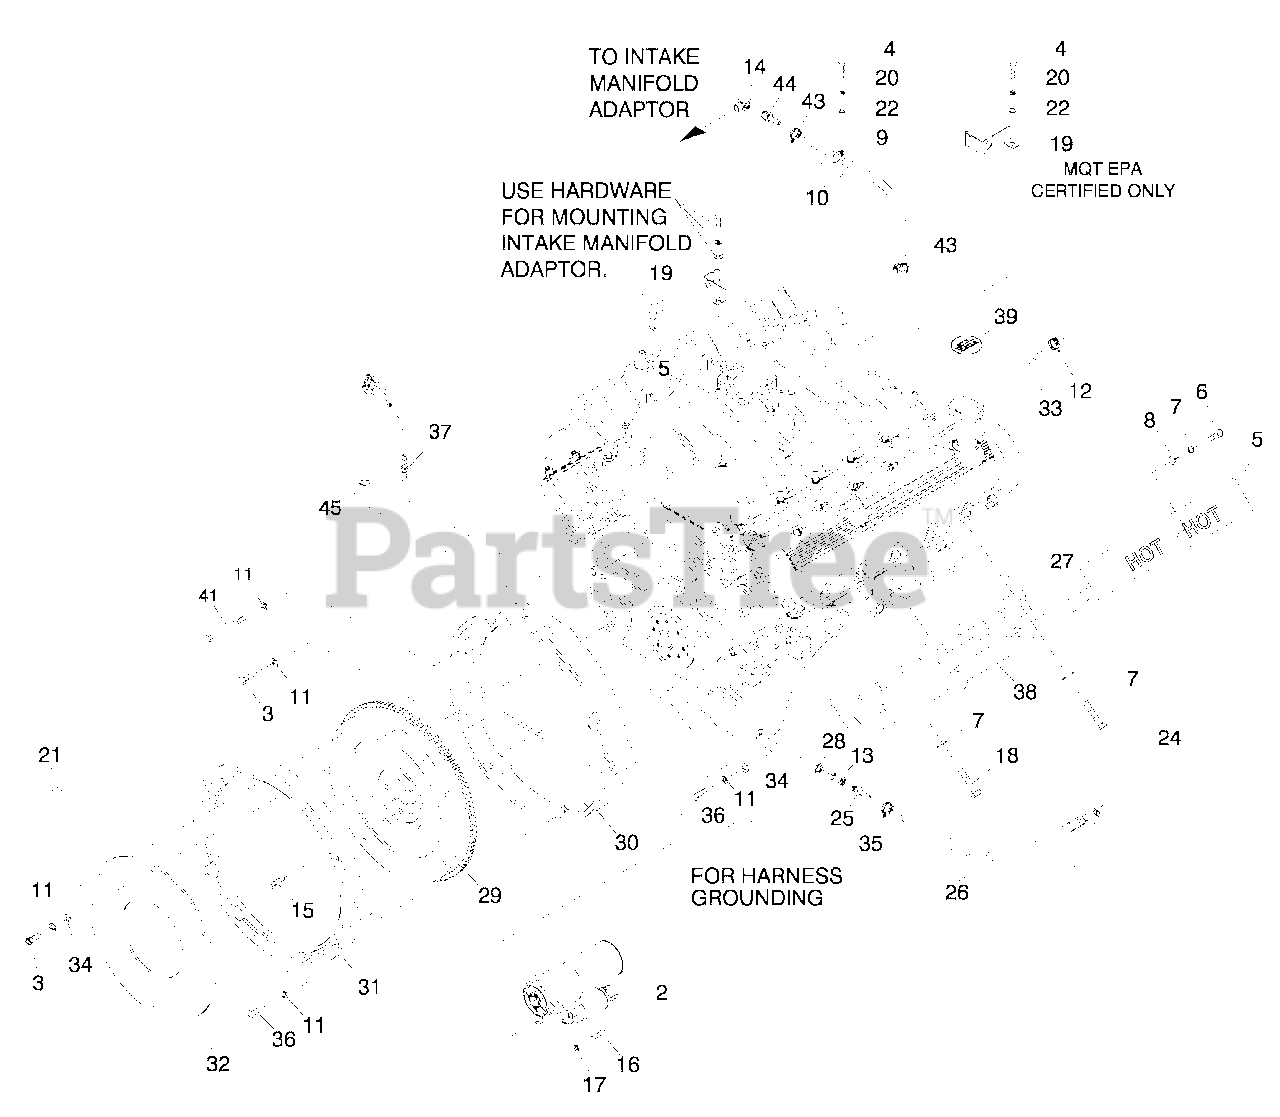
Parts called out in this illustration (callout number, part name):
2	STARTER MOTOR FORD V-10 ENGINE
3	SCREW SHC M10-1.5X 35 G12.9
4	SCREWHHCM6-1.0 X16G8.8
5	HEAT SHIELD EXHAUST
6	SCREW HHC 916-18X 1/2 SSTL
7	WAS HER LOCK M8SSTL
8	WAS HER FLAT M8 SS
9	CLAMPVINYL .75X.343Z
10	HOSE COOL 5(8" ID 250)WP (14")
11	WAS HER LOCK M10
12	CLAM PHOSE #10.56 - 1.06 (2300 & 3000RPM UNTSONLY)
13	ADAPTERM14-1.50 X3/8NPT
14	ELBOW 90D 1/4 NPT F-M BRASS
15	SCREW HHCM10-1.0 X 25 G10.9
16	SCREW SHC M8-1.25X30G12.9
17	WAS HER LOCK M8-5/16
18	SCREW HHCM 8-1.25 X 35 SSF-TH
19	BRACKET SIGNAL CONDITIONER
20	WAS HER LOCK M6-1/4
21	DOWEL PIN M10X24
22	WAS HER FLAT 1/4 ZINC
23	TIE WRAP UL7.4" X .19" BLK (NOTSHOWN)
24	SCREW SHC M8-1.25X35SS
25	BARBED STR 3/8NP TX3/8
26	HOSE DRAIN ASSY 28"
27	GASKET EXHAUST MANIFOLD
28	WAS HER NYLON .565
29	ASSEMBLY 68L G-BOX FLYWHEEL
30	FLYWH EE L H OUSING MAC H 6.8L V 10
31	COVER FLYWHEEL MACH 6.8L V-10
32	PLATE DAMPNER RETNR
33	CAP HOSE (2300 & 3000RPM UMTS ONLY)
34	WAS HER FLAT 3/8-M10 ZINC
35	CLAM PHOSE .38-.87
36	SCREW SHC M10-1.5X 25 G12.9
37	ASSY MAG PI CK U P(3/8-24 M ALE)
38	EXH MAN FOLD MACH 6.8L V-10
39	DECAL REFER TO OWNERS MANUAL
41	SCREWSHC M10-1.50X 100 G10.9
43	CLAM PHOSE #10.56-1.06
44	BARBED STR 1/4NPTX 5/8
45	PLUG PLASTIC 3/8 NPT
